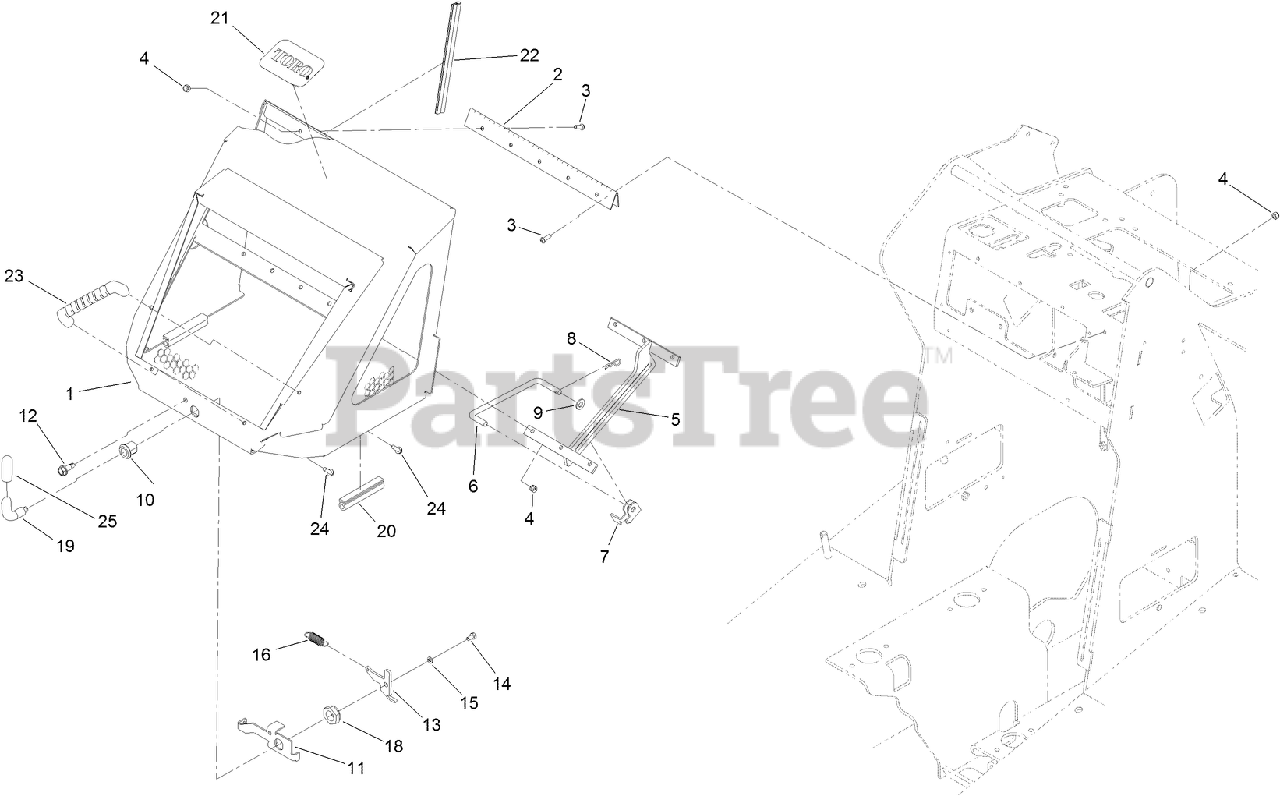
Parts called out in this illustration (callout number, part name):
1	ENGINE HOOD ASM
2	HINGE-HOOD
3	SCREW-HSBH
4	NUT-LOCK, NI
5	BRACKET-PROP, HOOD
6	ROD-SUPPORT, HOOD
7	BRACKET-LATCH, LOCKING
8	PIN-COTTER
9	WASHER-FLAT
10	HOUSING-LATCH
11	BRACKET-LATCH
12	Screw-Tapping
13	CAM-HOOKED
14	SCREW-HH
15	WASHER-LOCK
16	SPRING
18	NUT-LOCK, NI
19	HANDLE-LATCH
20	PAD-HOOD
22	TRIM-SEAL, BULB
23	HANDLE-DOOR
24	SCREW-HWH
25	GRIP-LEVER, HOOD
